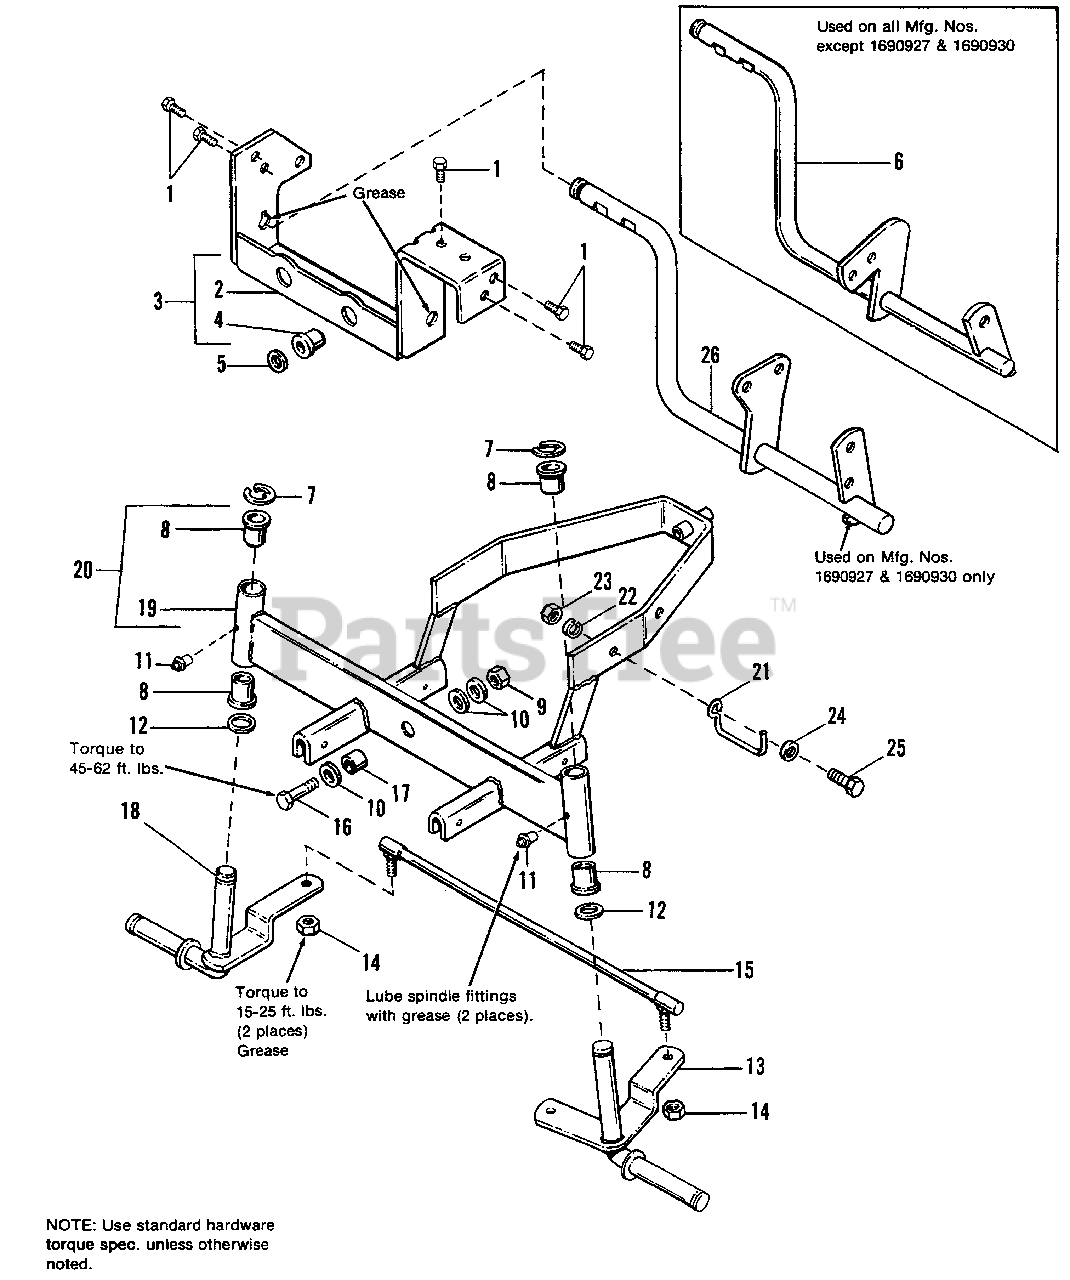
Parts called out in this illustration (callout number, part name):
1	SCREW, Taptite, 5/16-18 x 3/4
3	SUPPORT ASSY., Axle Rear w/Bushing
5	WASHER, 5/8
6	LEVER ASSY., Brake
7	E-RING, Ext., 3/4 Dia.
9	LOCKNUT, Hex, 1/2-13
10	WASHER, Plain, 9/16
11	FITTING, Grease, 1/4-20
13	* SPINDLE ASSY., L.H.
14	LOCKNUT, Hex, Gr. "B", 3/8-24
15	ROD ASSY, Tie
16	CAPSCREW, Hex, 1/2-13 x 2-1/4
18	SPINDLE ASSY., R.H.
20	AXLE ASSY., Front (Incl. Ref. Nos. 8 & 19)
21	GUIDE, Drag Link
22	LOCKWASHER
23	NUT, Hex, Full, 5/16-18
24	WASHER, 5/16 Std.
25	CAPSCREW, Hex, 5/16-18 x 1
26	LEVER ASSY., Brake
